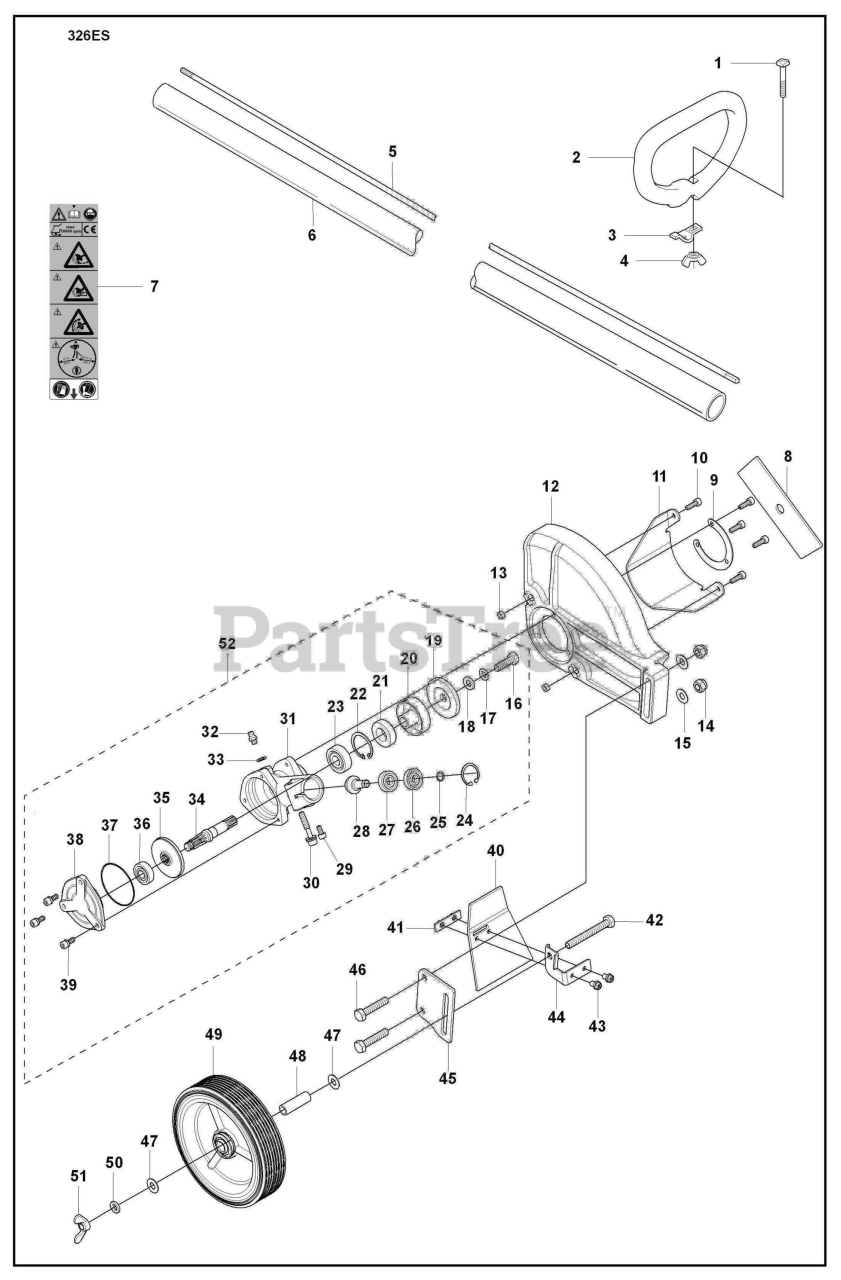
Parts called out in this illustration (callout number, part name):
2	HANDLE, LOOP
3	HOLDER
5	DRIVE SHAFT
6	DRIVE TUBE ASSEMBLY
7	DECAL, SAFETY
8	Blade, 7.52 X 2 X .125
10	BOLT M5 X L16 ALLEN
11	PLATE, PROTECTOR
14	NUT
16	BOLT M8 X L25 L/H
19	HOLDER (B)
20	HOLDER (A)
24	RP_RING
29	BOLT M5 X L10 ALLEN BOLT
30	BOLT M6 X L35 ALLEN
39	BOLT M5 X L14 ALLEN
42	BOLT M8 X L65
43	BOLT M5 X L10
45	MAIN BRACKET
46	BOLT M8 X L40
51	RP_NUT
52	GEARCASE ASSY
